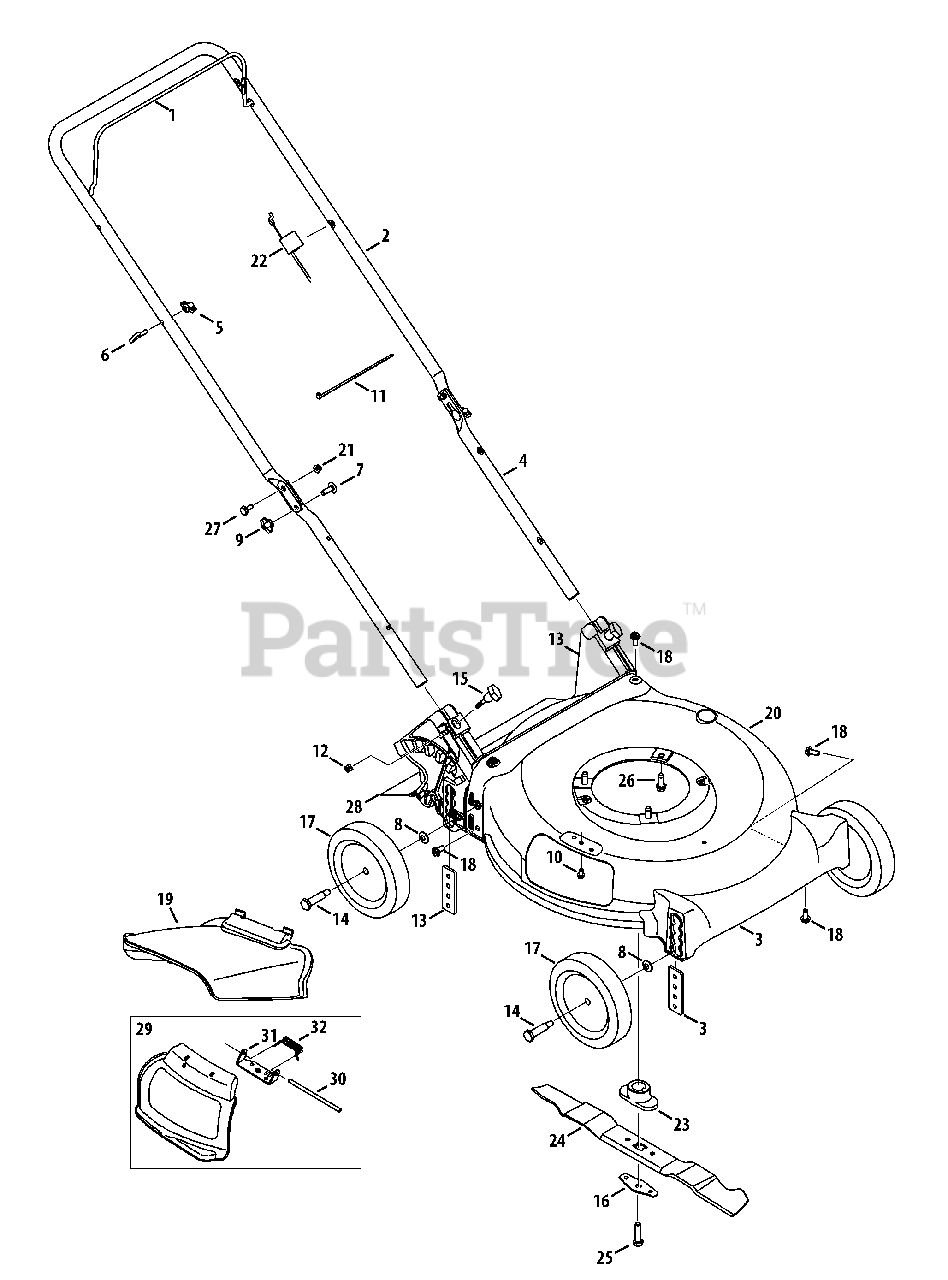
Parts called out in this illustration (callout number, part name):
1	Blade Control
2	Upper Handle
3	Front Cover Assembly
4	Lower Handle
5	Wing Nut
6	Rope Guide
7	Carriage Screw ,5/16-18
8	Washer, .401 x .870 x .060
9	Wing Knob
10	Screw, 1/4-20 x .500
11	Cable Tie
12	Nut, Sq., 1/4-20
13	Rear Baffle
14	Shoulder Screw
15	Wing Nut
16	Blade Bell Support
17	Wheel, 7" Star-Dia., Oys. Gray
18	Screw, 5/16-14 x .750
19	Side Chute
20	Deck , 21"
21	Nut, Flange Lock, 1/4-20
22	Control Cable
23	Blade Adapter
24	Mulching Blade
25	Screw , 3/8-24 x 1.50
26	TT Sems Screw, 3/8-16 x 1.0
27	Sldr. Screw, .375 x .126 x 1/4-20
28	Trail shield
29	Hinged Mulch Plug Assembly
30	Hinge Pin
31	Chute Deflector Bracket
32	Torsion Spring
